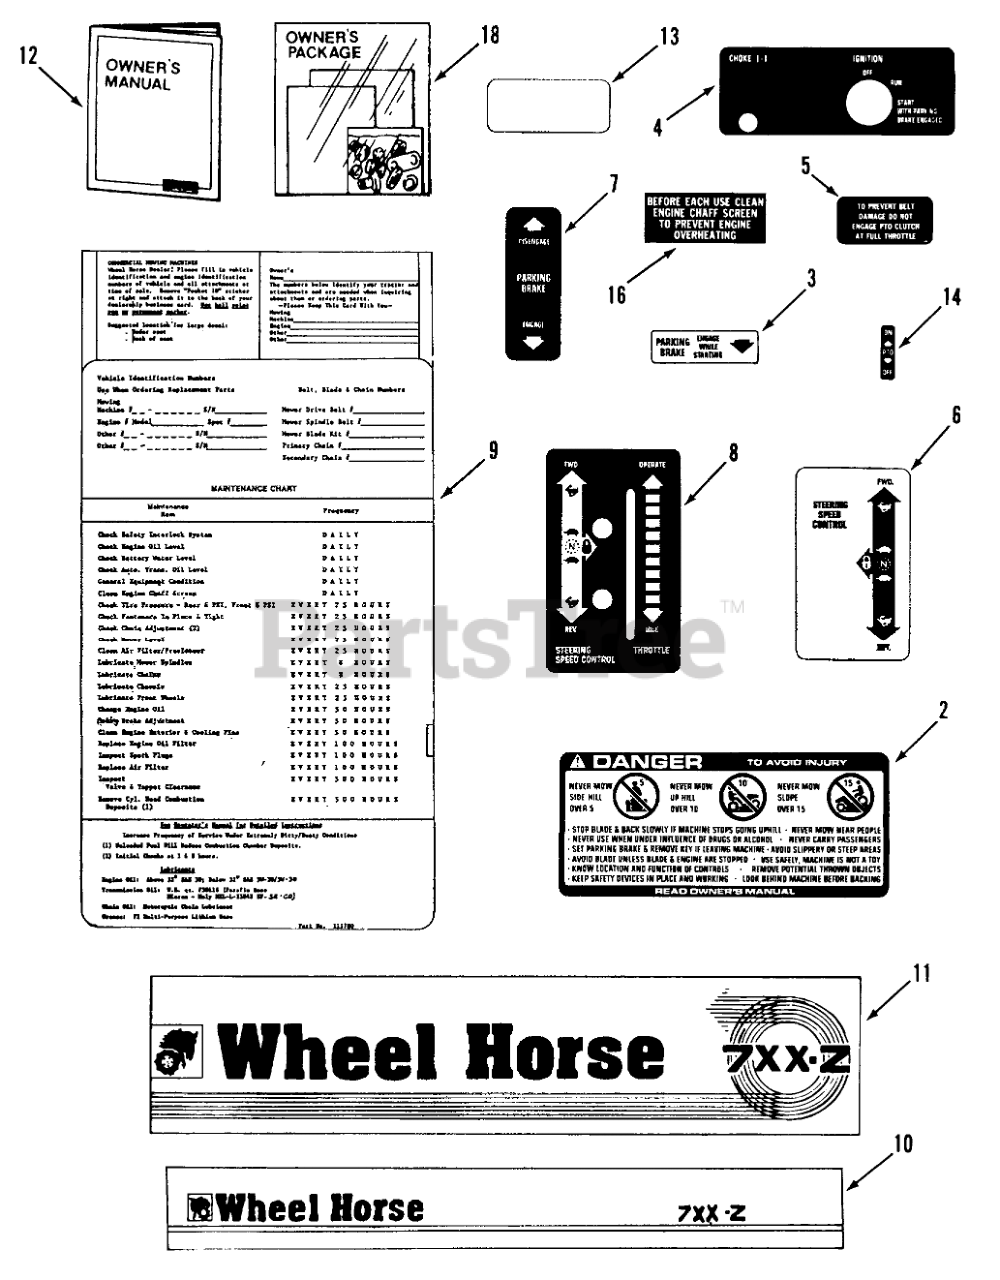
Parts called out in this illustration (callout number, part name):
2	DECAL-DANGER
3	DECAL-PARKING BRAKE
4	DECAL-CHOKE/IGNITION
9	MAINTENANCE-DECAL
11	DECAL-FENDER L.H.
12	700-Series Owner-s Manual
13	DECAL-OVERLAY
14	DECAL-PTO
